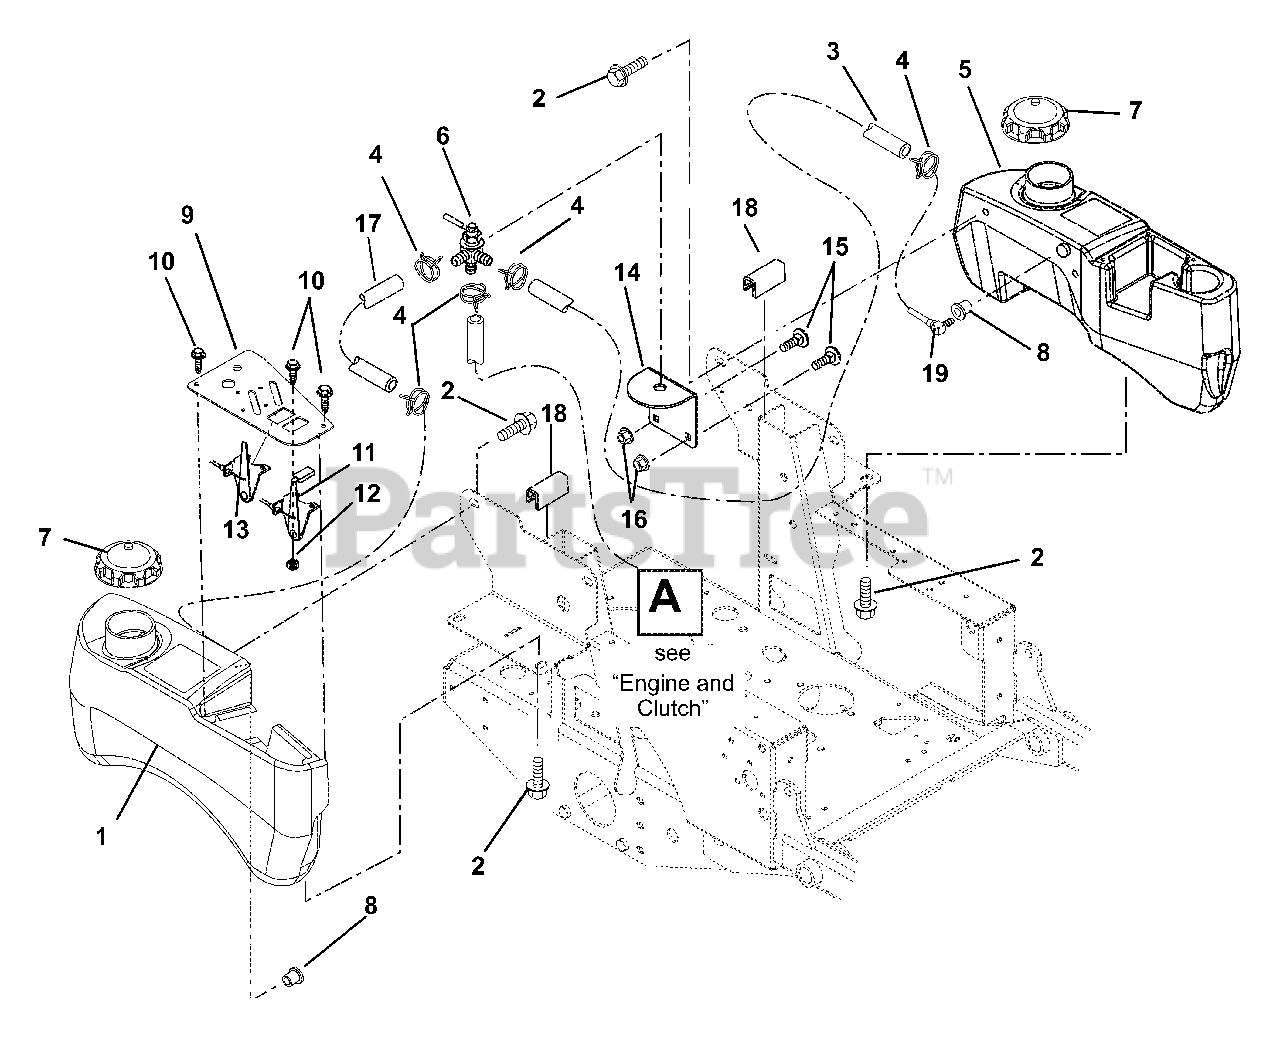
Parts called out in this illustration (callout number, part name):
1	TANK, FUEL RH W/O HOSE
2	BOLT, SEMS .31-18 X .62
3	GAS LINE-BULK 1/4" I.D.
4	CLAMP-HOSE WIRE .490/.510X.116
5	TANK, LH FUEL CZ W/O HOSE
6	VALVE, FUEL
7	CAP - FUEL
8	GROMMET, DAPCO VITON #12240
9	PANEL, CONTROL
10	@SCR-MCH 10-24X.50 HWH YWZC
11	CABLE, THROTTLE
12	@NUT-LK-NYL 10-24 W/INSRT YWZC
13	CABLE, CHOKE
14	BRKT, FUEL VALVE MNTG
15	@BLT-RDHDSQNK .31-18X.75 G5YZ
16	@NUT-LK-NYL-FLG .31-18 YWZC
17	GAS LINE-BULK 1/4" I.D.
18	STRIP, COWL
19	FITTING, TANK ELBOW .31 HOSE
